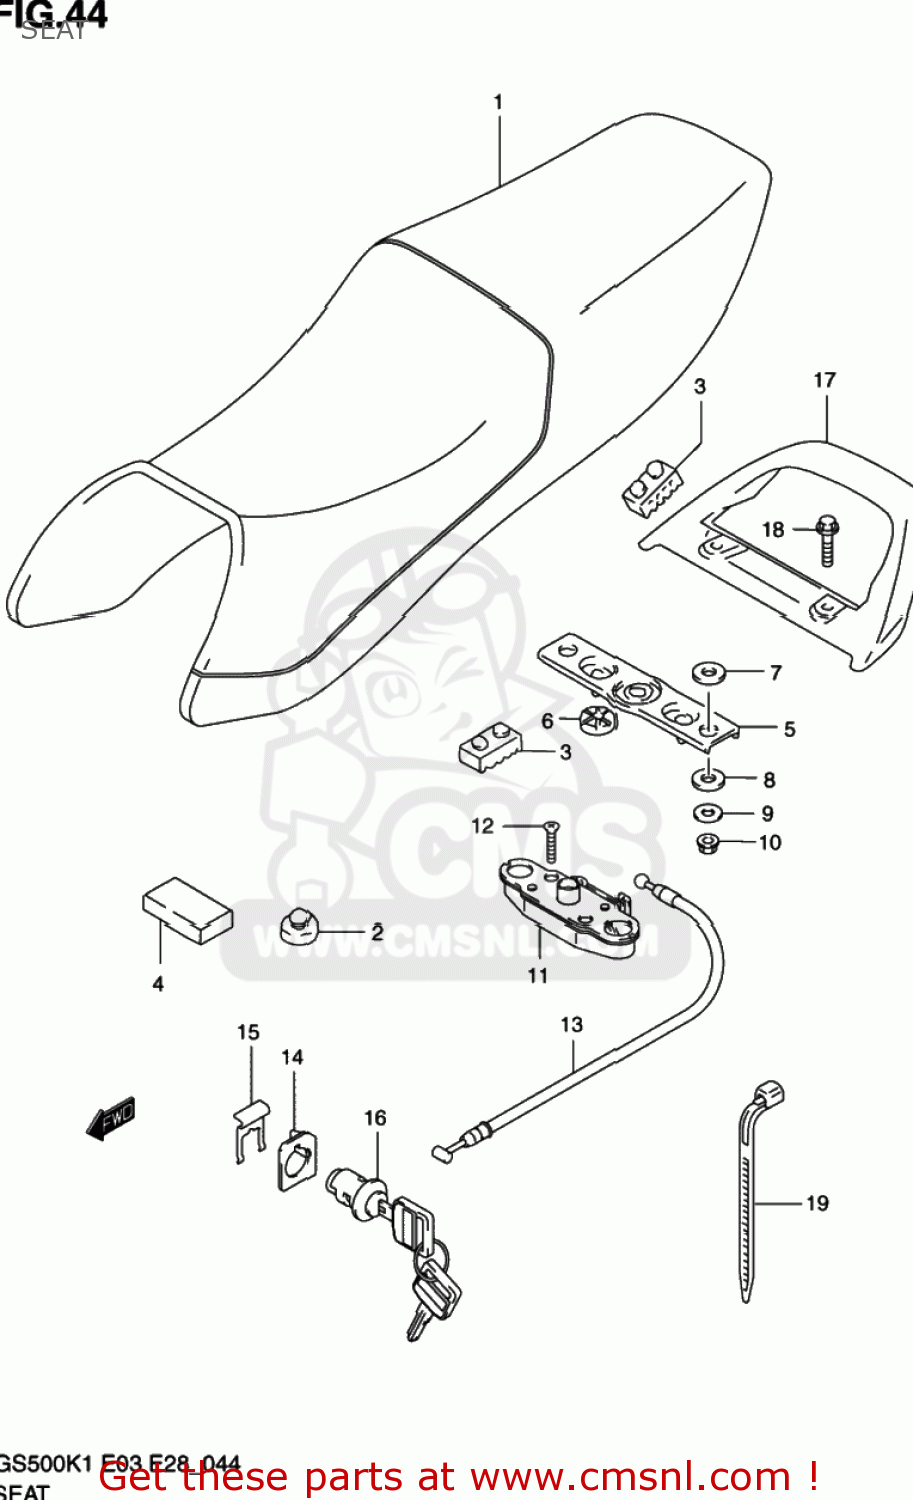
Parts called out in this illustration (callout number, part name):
1	SEAT ASSY
2	CUSHION
3	CUSHION,SEAT(40X20X15)
4	CUSHION(30X60X10)
5	STRIKER,SEAT LOCK
6	CUSHION,SEAT LOCK(10X22X6)
7	CUSHION,UPR
8	CUSHION,LWR
9	WASHER
10	NUT
11	BRACKET,SEAT SUPPORT,RIGHT
12	SCREW
13	CABLE,SEAT LOCK
14	GUIDE,SEAT LOCK CABLE
15	PLATE,SEAT LOCK ASSY
16	LOCK SET,SEAT
17	HANDLE,PILLION RIDER
18	BOLT
19	CLAMP(L:165)
